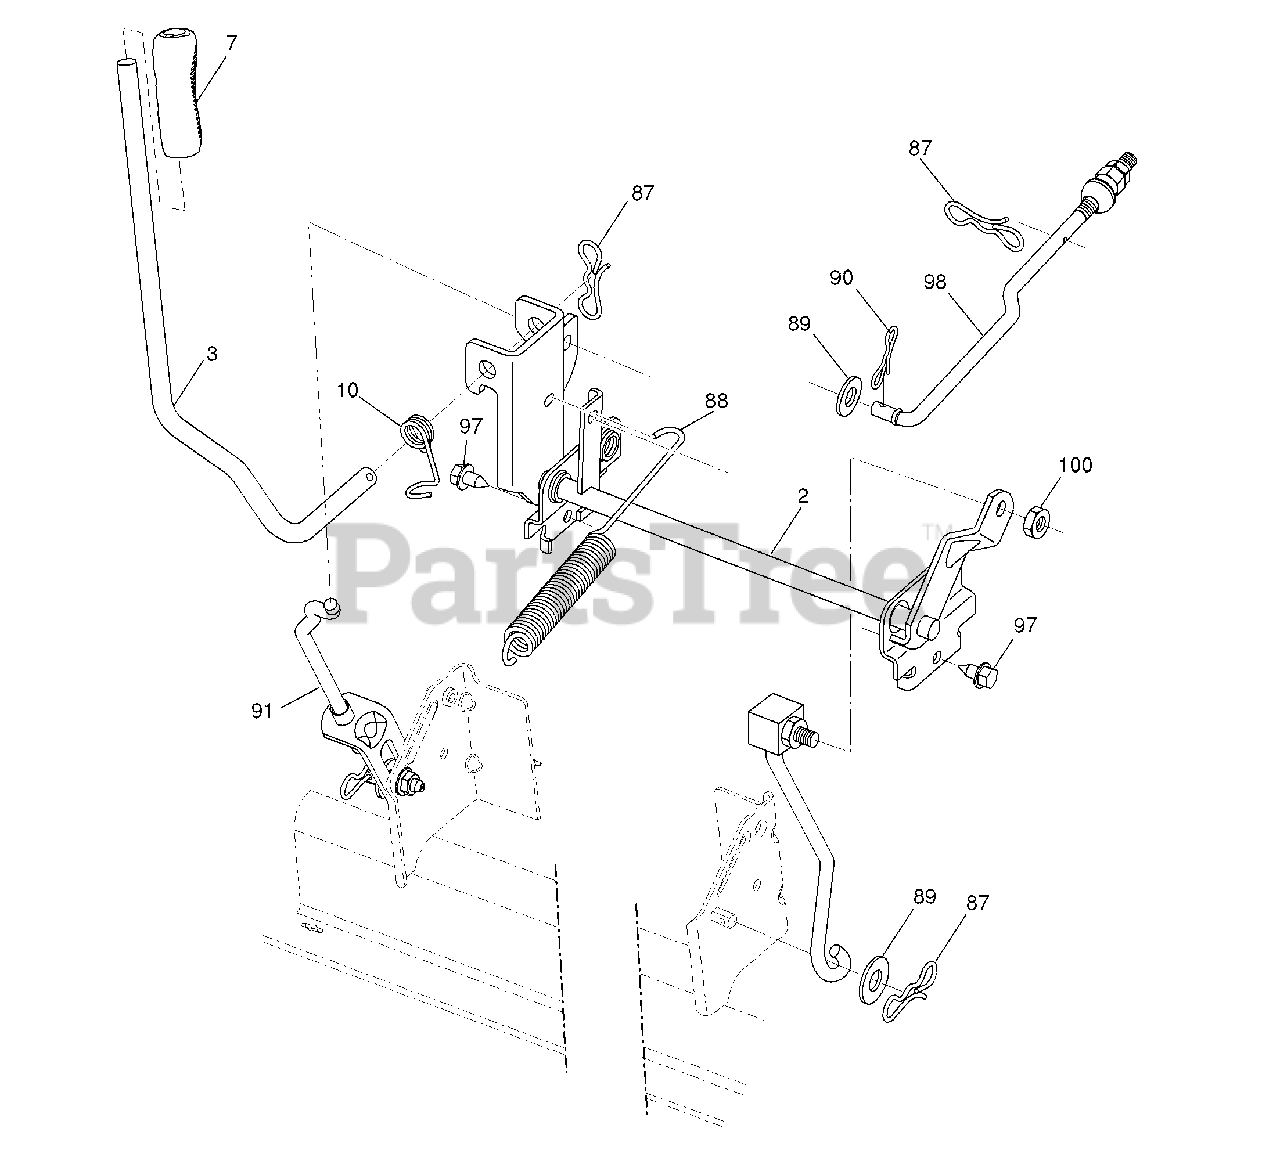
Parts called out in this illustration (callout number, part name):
2	Shaft Asm., Lift
3	Lever Asm., Lift Rh
7	Grip, Lever
10	Spring Torsion
87	Pin Cotter 7/16 Bow Tie Lock
88	Spring Lift Assist
89	Washer Clear Zinc
90	Pin Cotter 5/16 Bow Tie Lock
91	Link Lift Susp Mower Rear
97	Screw 3/8-16 x .75 Smgml Tap/R.Z
98	Link Lift Susp. Front Mower
100	Nut Center Lock 3/8-16 UNC
